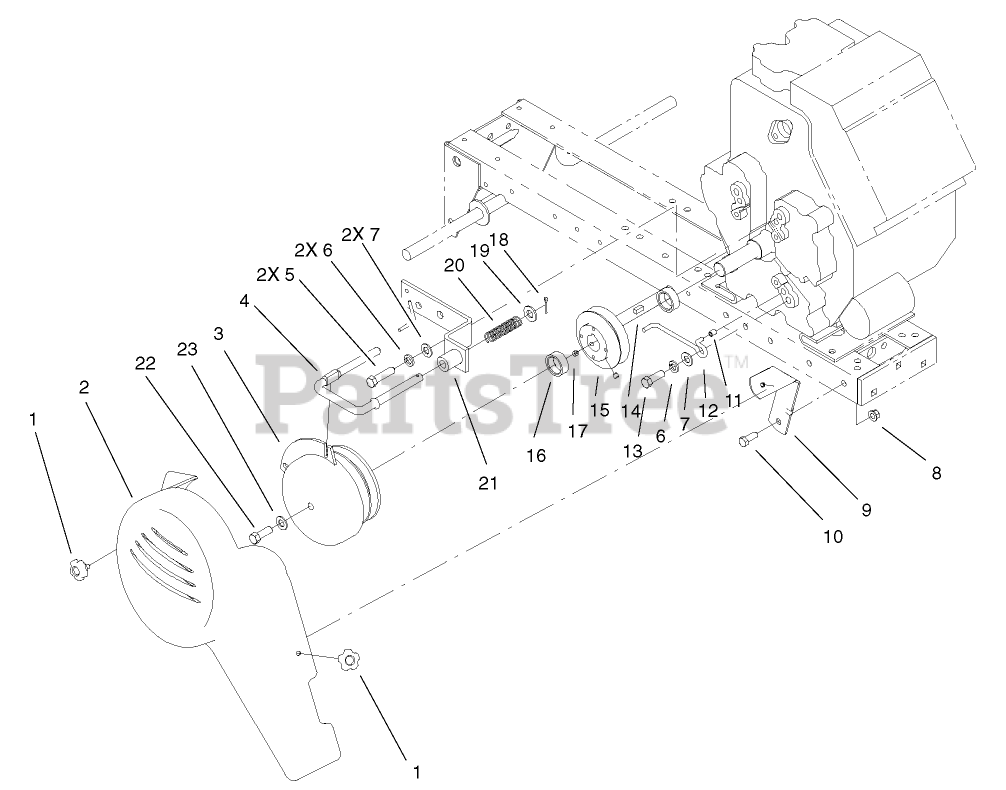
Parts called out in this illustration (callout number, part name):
2	GUARD-BELT
3	CLUTCH-ELECTRIC, CLASSIC
4	ROD-STOP, PTO
6	WASHER-LOCK
7	WASHER-FLAT
8	NUT-HHF, WHIZ
9	BELT COVER BRACKET ASM
10	SCREW-HH
12	WIRE-GUIDE, BELT
13	SCREW-HH
15	PULLEY
16	SPACER-CRANKSHAFT
17	SCREW-SET, HSH
18	PIN-COTTER
19	WASHER-FLAT
20	SPRING-COMPRESSION
21	PTO STOP ASM
